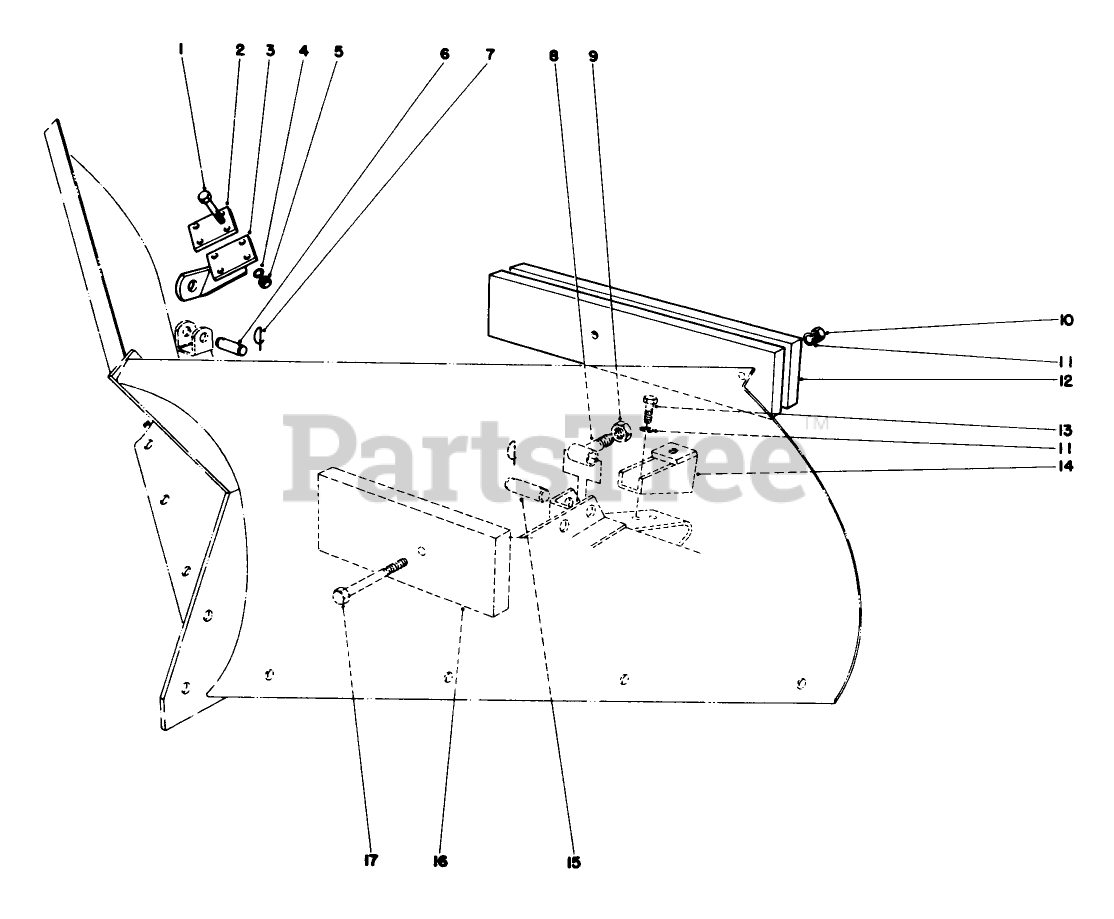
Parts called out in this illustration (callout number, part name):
1	SCREW-HH
2	Camp Plate
3	Push Arm Bracket
4	WASHER-LOCK
5	NUT-HEX
6	Pin
7	PIN-LYNCH
8	Push Pin
9	NUT-HJ
10	NUT-HH
11	WASHER-LOCK
12	Outside Weight
13	SCREW-HH
14	Stop
15	PIN-PLAIN
16	Inside Weight
17	SCREW-HH
